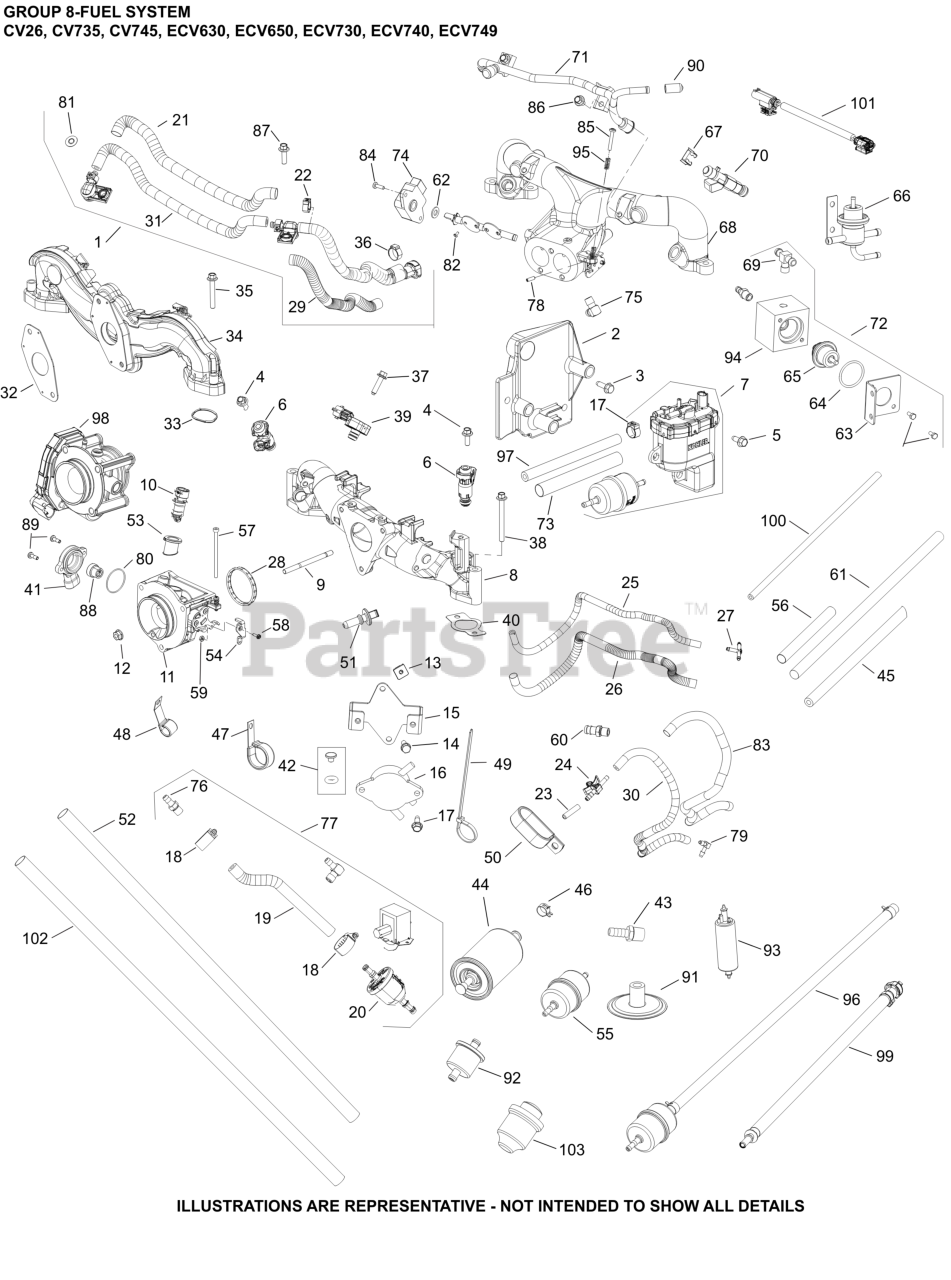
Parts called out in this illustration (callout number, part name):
1	FUEL HOSE ASSY(ECV,FCV,EZT,EKT,PCH,PCV)
2	KIT,BAFFLE, FUEL MODULE
3	SCREW, THREAD FORMING
5	SCREW, FLG M6X1.0X16
6	INJECTOR, FUEL
7	KIT, FUEL PUMP MODULE
8	KIT, MANIFOLD
9	STUD,M6X1.0X84
11	BODY, THROTTLE ASM (30)
13	NUT, PLASTIC - BLACK
14	SCREW, HEX HEAD
15	BRACKET, FUEL PUMP MOUNTING
16	PUMP, FUEL
17	SCREW, THREAD FORMING
19	HOSE,LW PERM.FUEL 24.00"-USE 25 111 81-S
22	CLAMP, OETIKER
23	CAP, MASKING
24	CONNECTOR, EVAPORATIVE
26	SLEEVE, ANTI-ABRASION
27	TEE CONNECTOR
28	O-RING, THROTTLE BODY
30	HOSE, EVAPORATIVE (15.0)
35	SCREW, FLG M6X1.0X40
36	CLAMP, HOSE
38	SCREW, FLG M6X1.0X60
39	SENSOR, T-MAP
40	KIT, INTAKE MANIFOLD GASKET
41	SENSOR, THROTTLE POSITION
42	KIT, FUEL INJECTOR O-RING
46	SPRING CLAMP, HOSE
52	SLEEVE, HEAT REFLECTIVE
55	FILTER, FUEL
80	O-RING, TPS SENSOR
81	CLIP, RETAINER
87	SCREW, FLG M6x1.0x20
88	MAGNET ASSEMBLY, TPS
97	HOSE, FUEL LOW-PERMEATION
